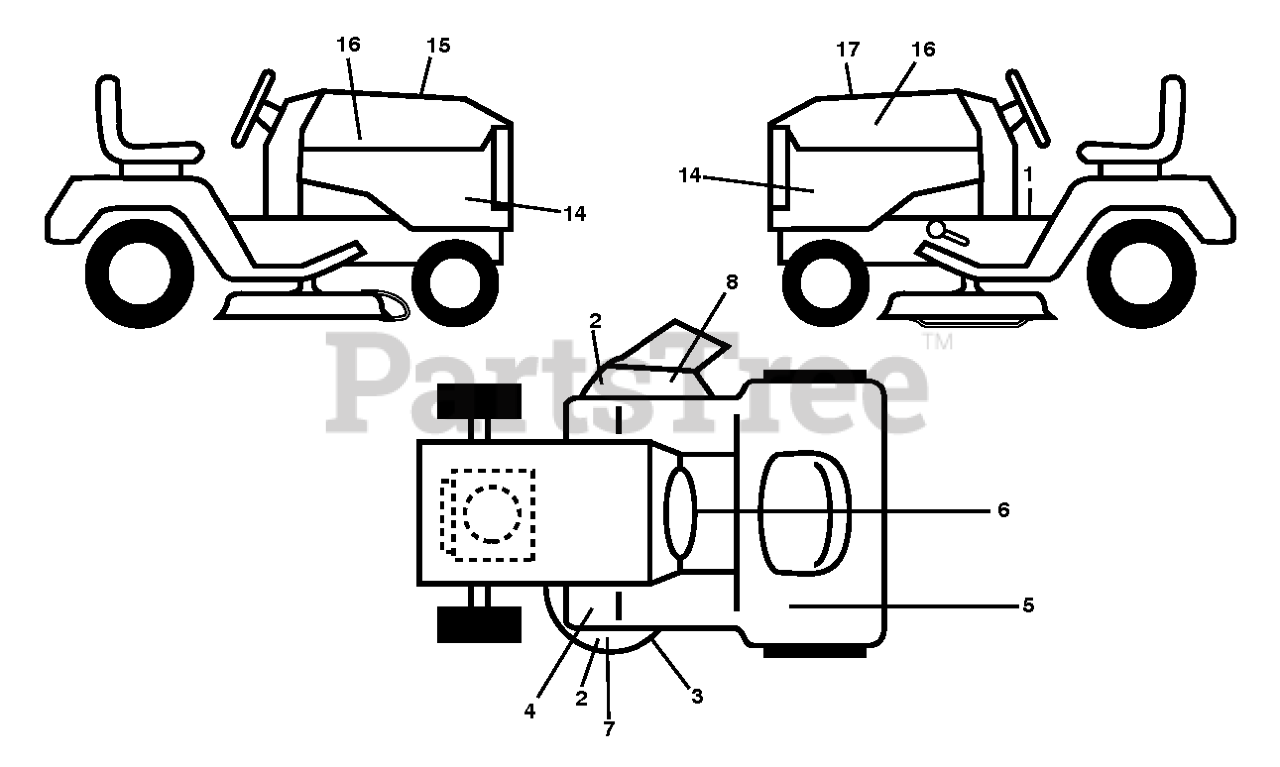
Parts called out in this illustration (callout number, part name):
1	DECAL.FENDER.WARNING.ENGLISH
2	DECAL.DECK.CLEARCUT.NOSTEP
3	DECAL DECK DECAL DECAL.DECK.WA
4	DECAL BELT ROUTING DECAL DECAL
6	DECALS.WARN.CA.SPKARREST/PROP
7	DECAL.54DECK.CLEARCUT.VER2.18
8	DECAL.TRACT/ZTR.DECKWARN.HUSQ
14	DECAL TRACTOR SIDE PANEL DECAL
15	DECAL.WARNING.CUST.RESP.E85.
16	DECAL.BADGE.170MM.TEXTLOGO.
17	DECAL.RPL.KW.FR7.TLB.54F
